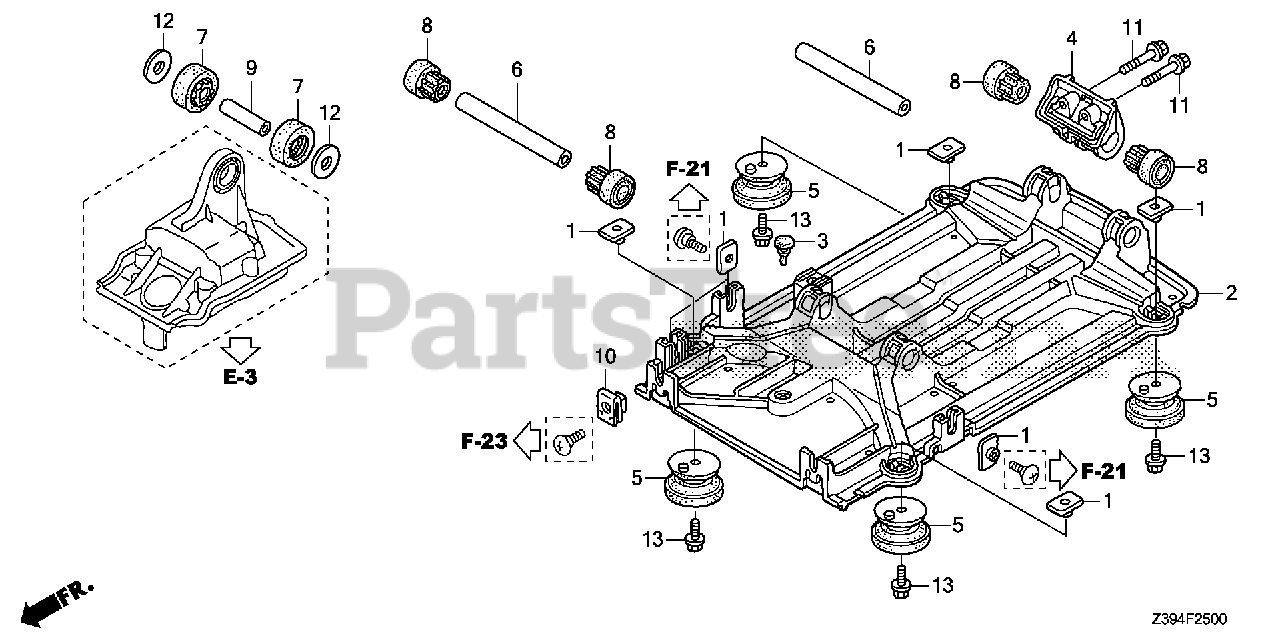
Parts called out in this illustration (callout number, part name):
1	NUT, SPECIAL (6MM)
2	COVER (LOWER)
3	GROMMET, PAD SETTING
4	BRACKET, ENGINE MOUNTING
5	RUBBER (LOWER)
6	COLLAR A, INSULATOR
7	INSULATOR (UPPER)
8	INSULATOR (LOWER)
9	COLLAR B, INSULATOR
10	NUT, FENDER SETTING
11	BOLT, FLANGE (6X32) (CT200)
12	WASHER, SPROCKET SETTING
13	BOLT, FLANGE (6X10)
